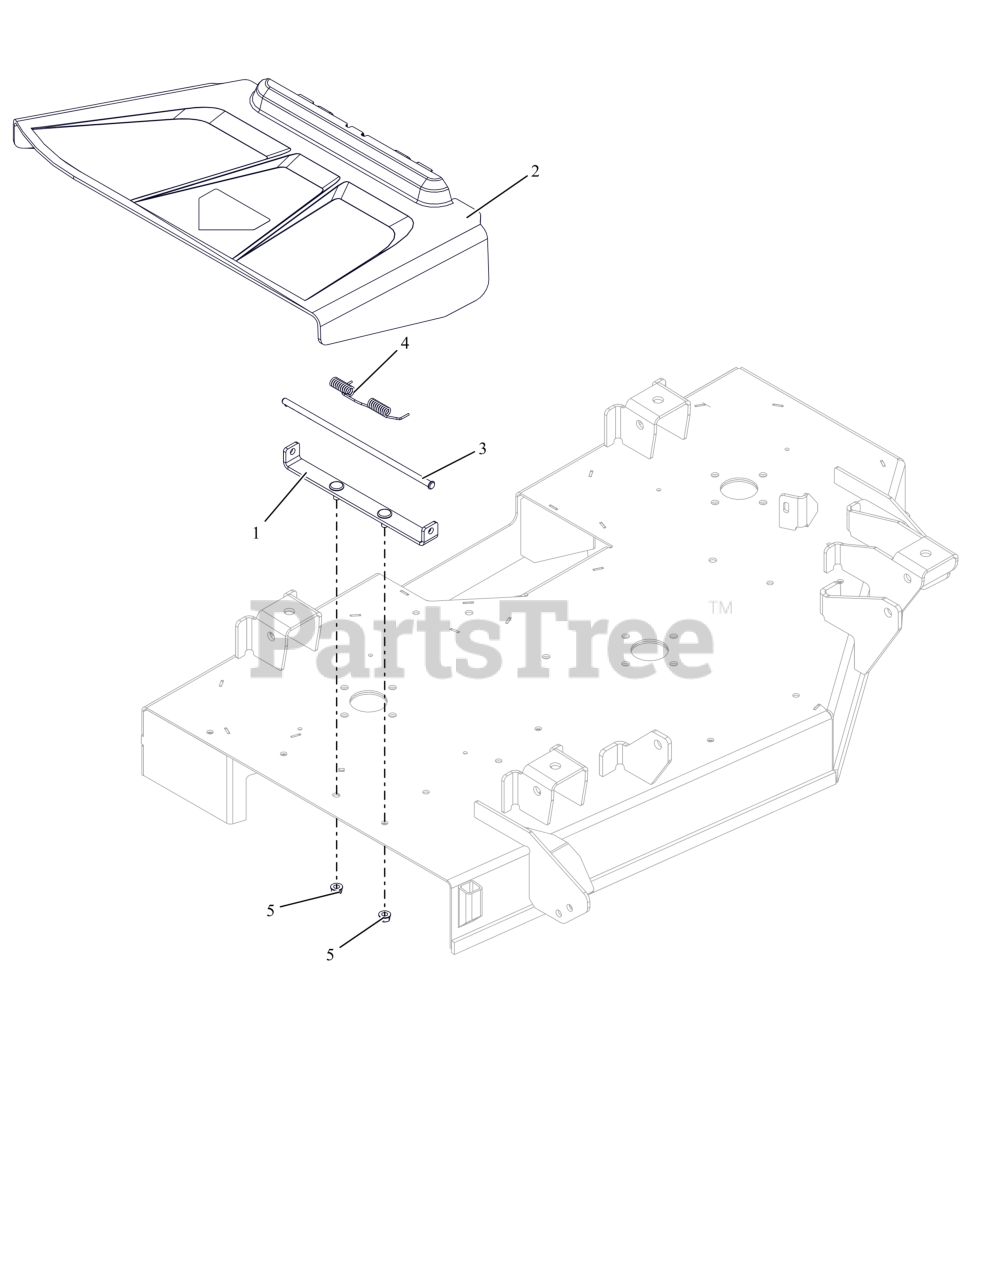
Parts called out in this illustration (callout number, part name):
2	CHUTE, SIDE DISCHARGE
3	PIN, SLIC-.312X10.45
4	SPRING-TORSION
5	NUT-LK-TOP-FLG .312-18 GF ZCC
